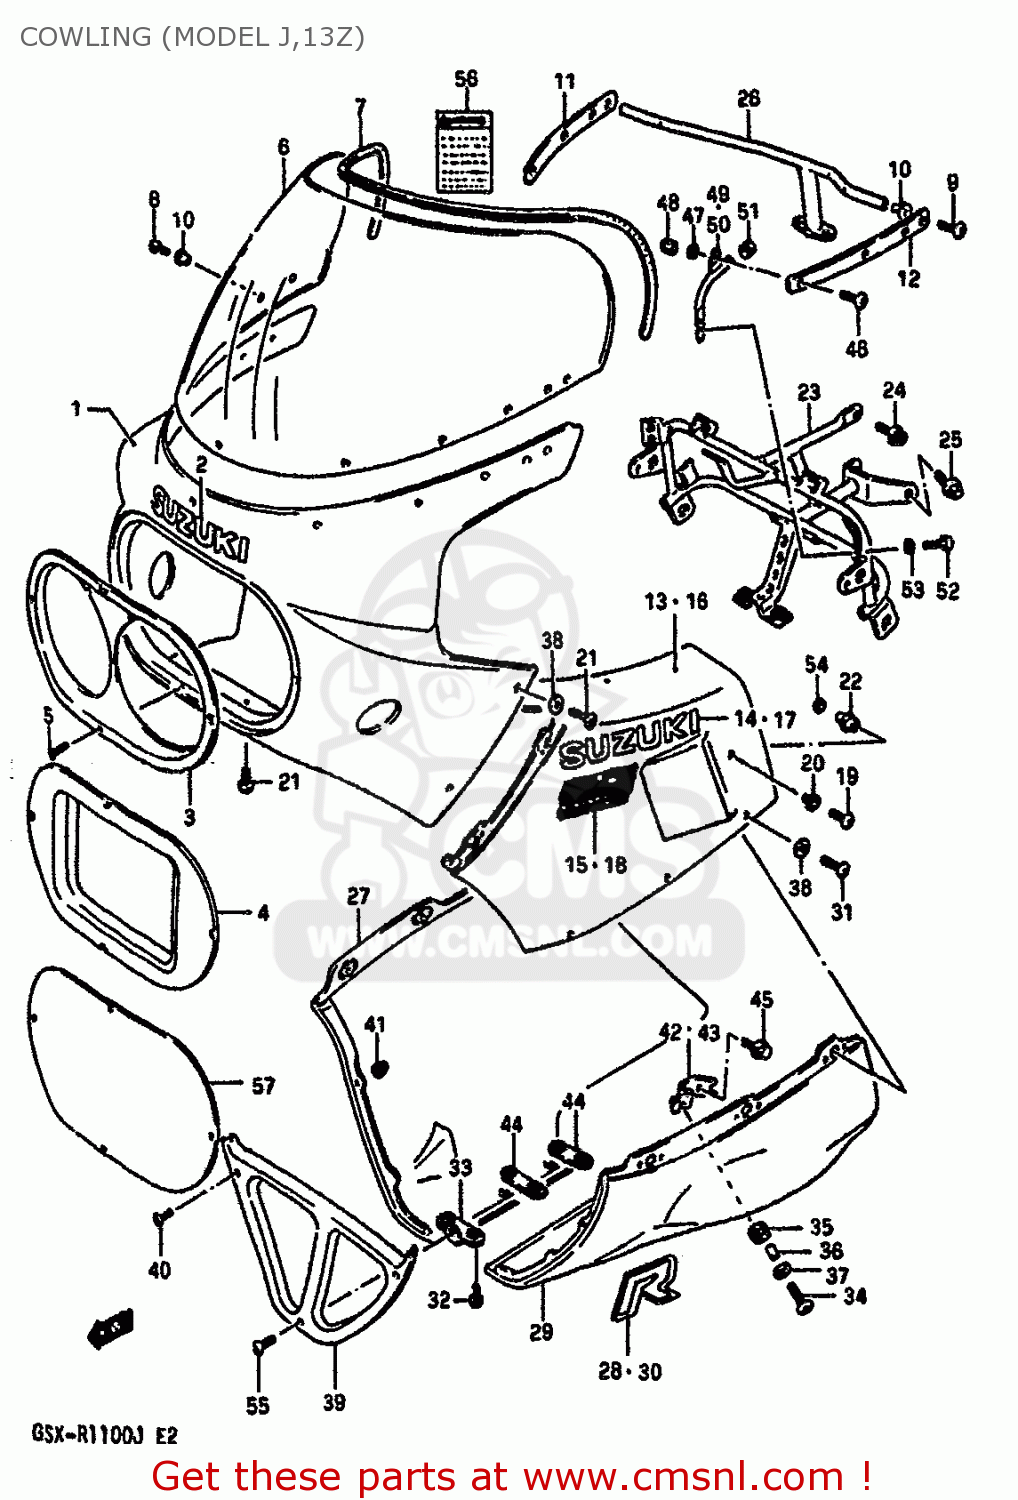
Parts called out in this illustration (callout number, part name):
1	BODY ASSY,COWLING (BLACK)
2	EMBLEM
3	COVER,COWLING FR
4	COVER,FRONT (BLACK)
5	SCREW
6	WINDSCREEN
7	MOLDING
8	SCREW(5X14)
9	SCREW(5X18)
10	NUT,COWLING SCREEN
11	PLATE,RR VIEW MIRROR,R
12	PLATE,RR VIEW MIRROR,L
13	COVER,SIDE RH (BLACK)
14	EMBLEM,COWLING SIDE
15	EMBLEM
16	COVER,SIDE LH (BLACK)
17	EMBLEM,COWLING SIDE
18	EMBLEM
19	SCREW(6X12)
20	WASHER
21	SCREW(6X16)
22	CUSHION,COWLING
23	BRACE,COWLING FR
24	BOLT
25	BOLT
26	BRACE,COWLING BODY RR
27	COVER,LOWER RH (BLACK)
28	EMBLEM,COWLING LWR
29	COVER,LOWER LH (BLACK)
30	EMBLEM,COWLING LWR
31	SCREW(6X16)
32	SCREW(6X16)
33	BRACE,COWLING LWR COVER
34	SCREW(6X20)
35	CUSHION
36	SPACER
37	WASHER(6.5X18X1)
38	WASHER
39	COVER,COWLING,LOWER,FRONT
40	SCREW(5X14)
41	NUT
42	BRACE,COWLING LWR,R
43	BRACE,COWLING LWR,L
44	BRACE,COWLING LWR COVER RR
45	BOLT
46	SCREW(6X16)
47	WASHER,LOCK
48	NUT 6MM
49	BRACE,MIRROR,R
50	BRACE,MIRROR,L
51	PLUG(OD:12)
52	BOLT 6X16
53	WASHER,LOCK
54	WASHER
55	SCREW(6X16)
56	LABEL (WARNING SCREEN)
57	COVER,HEADLAMP
